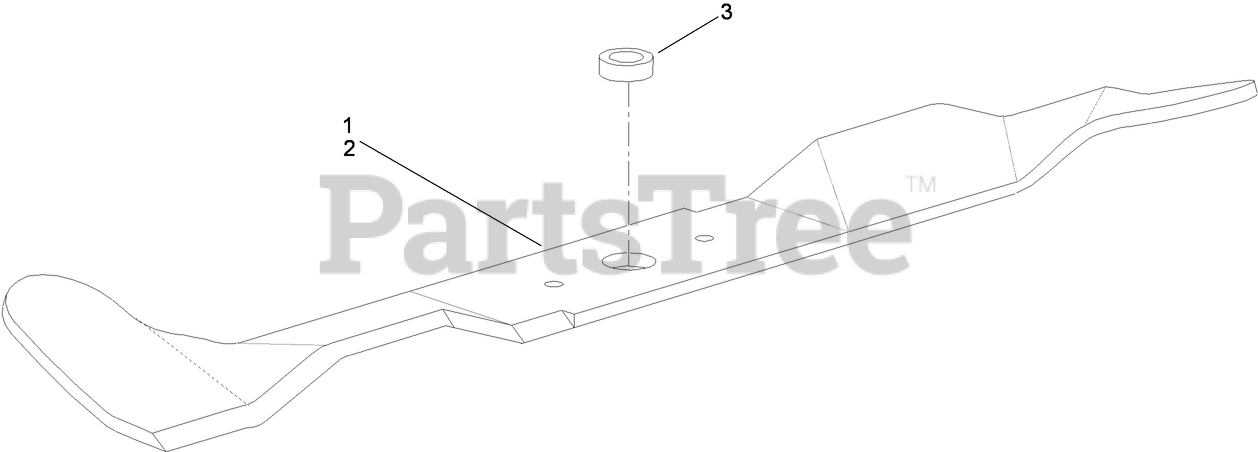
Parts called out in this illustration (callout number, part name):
1	BLADE-RIGHT, BAGGING
2	BLADE-LEFT, BAGGING
3	SPACER
